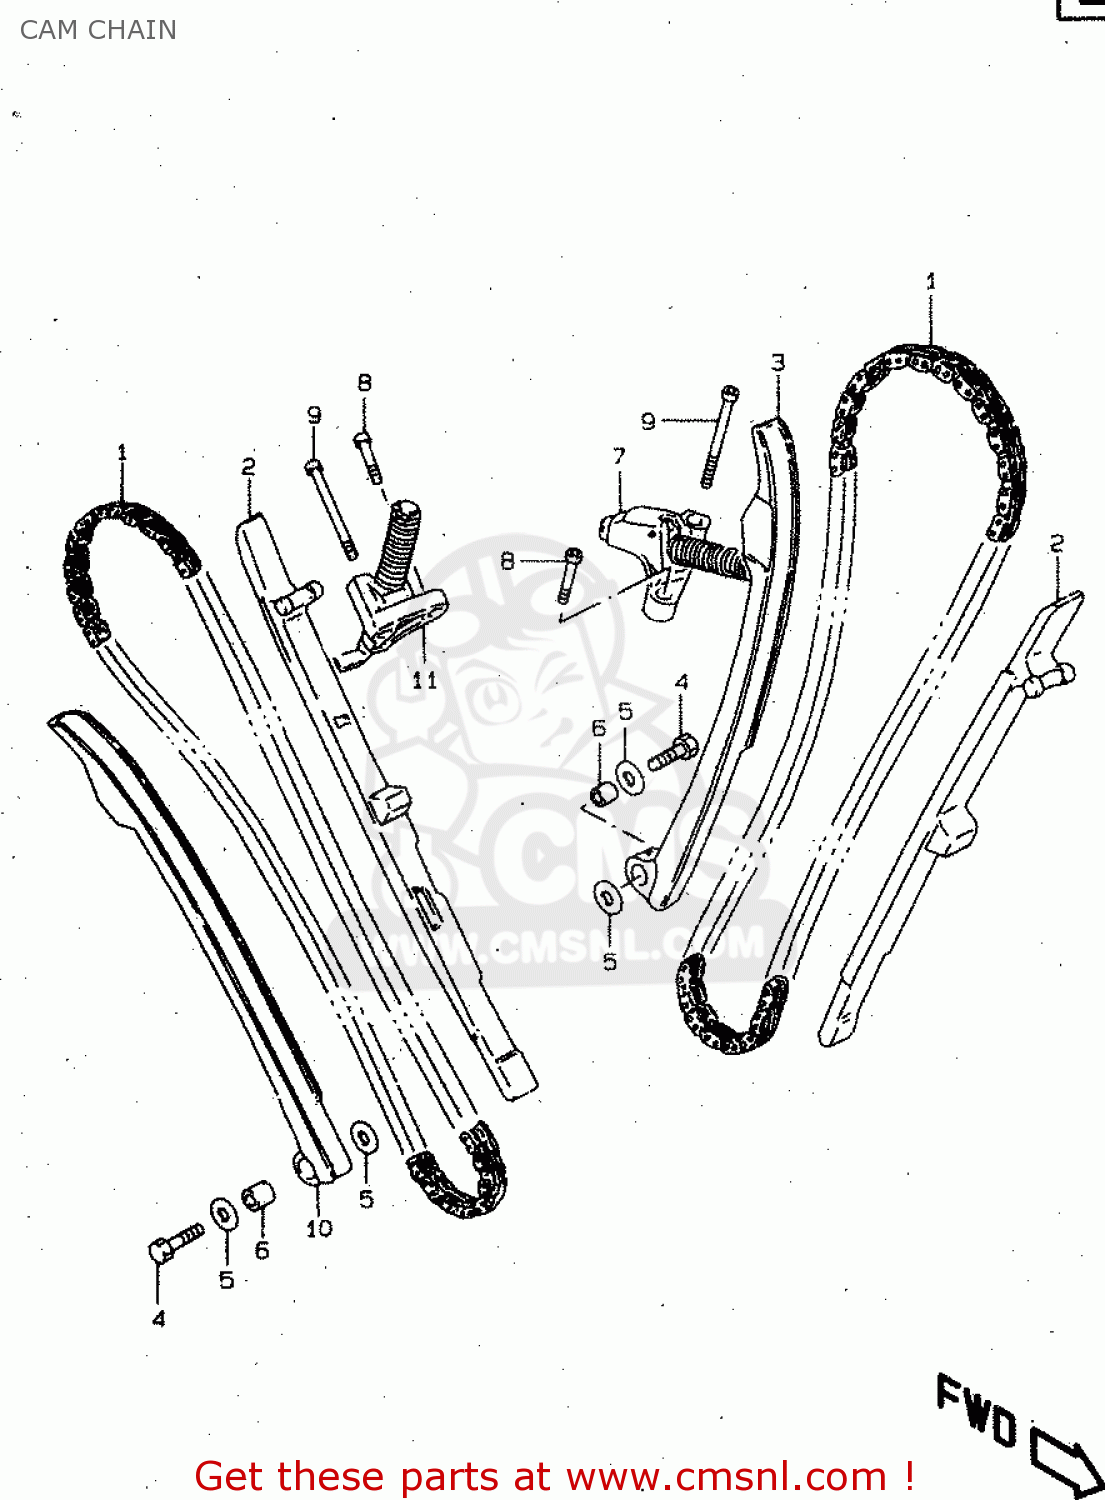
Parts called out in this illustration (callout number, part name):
1	CHAIN COMP,CAMSHAFT DRIVE
2	GUIDE,CAM CHAIN
3	TENSIONER,FR CAM CHAIN
4	BOLT(6X26)
5	WASHER
6	SPACER(6X11X11)
7	ADJUSTER ASSEMBLY,FRONT TENSIONER
8	BOLT,CRKCASE,R
9	BOLT
10	TENSIONER,RR CAM CHAIN
11	ADJUSTER ASSEMBLY,REAR TENSIONER
